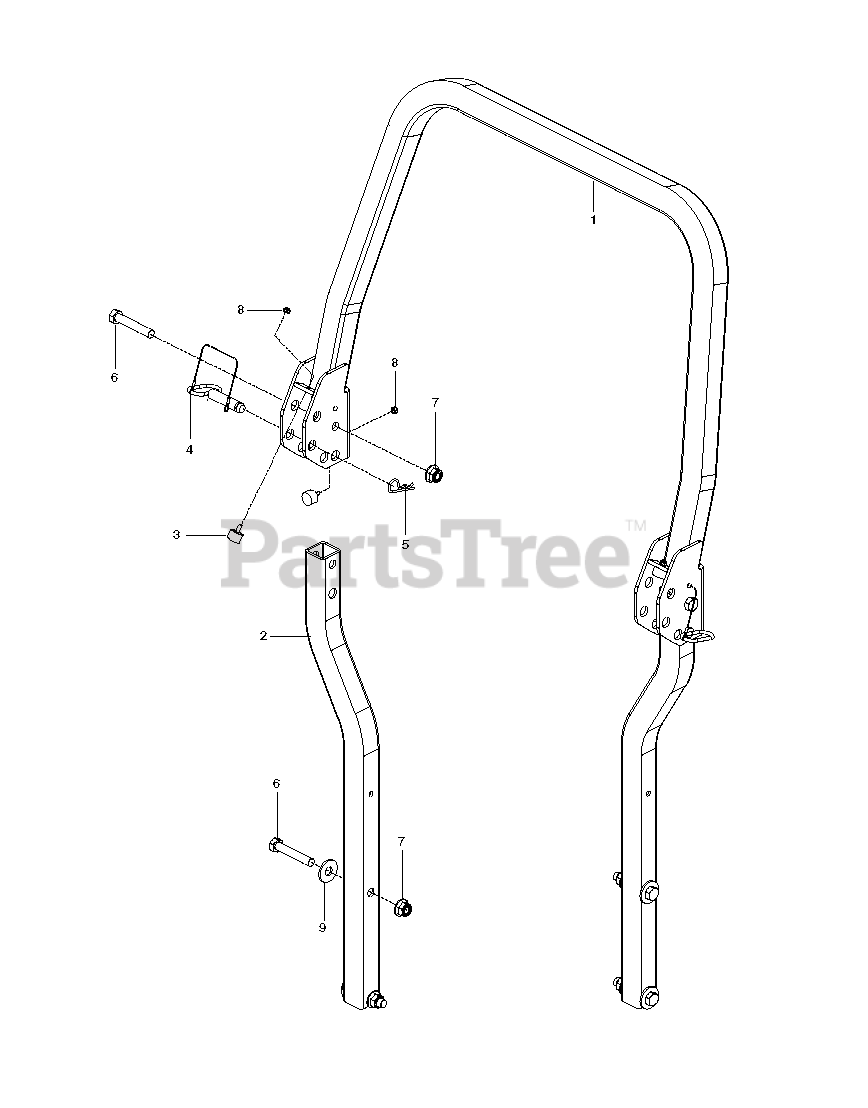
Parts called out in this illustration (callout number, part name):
1	ROPS TOP GRAY
2	TUBE.SIDE.ROPS.GREY
3	BUMPER, MALE STUD, 1/4-20
5	PIN HAIR .148 X 2-15/16 #210
6	5/8-11 X 3-1/2 HHB GRADE 5
7	NUT 5/8-11 FLG NYLOC ZD
8	RP_NUT 1/4-20 NYLOC
9	WASHER, 5/8 FLAT
